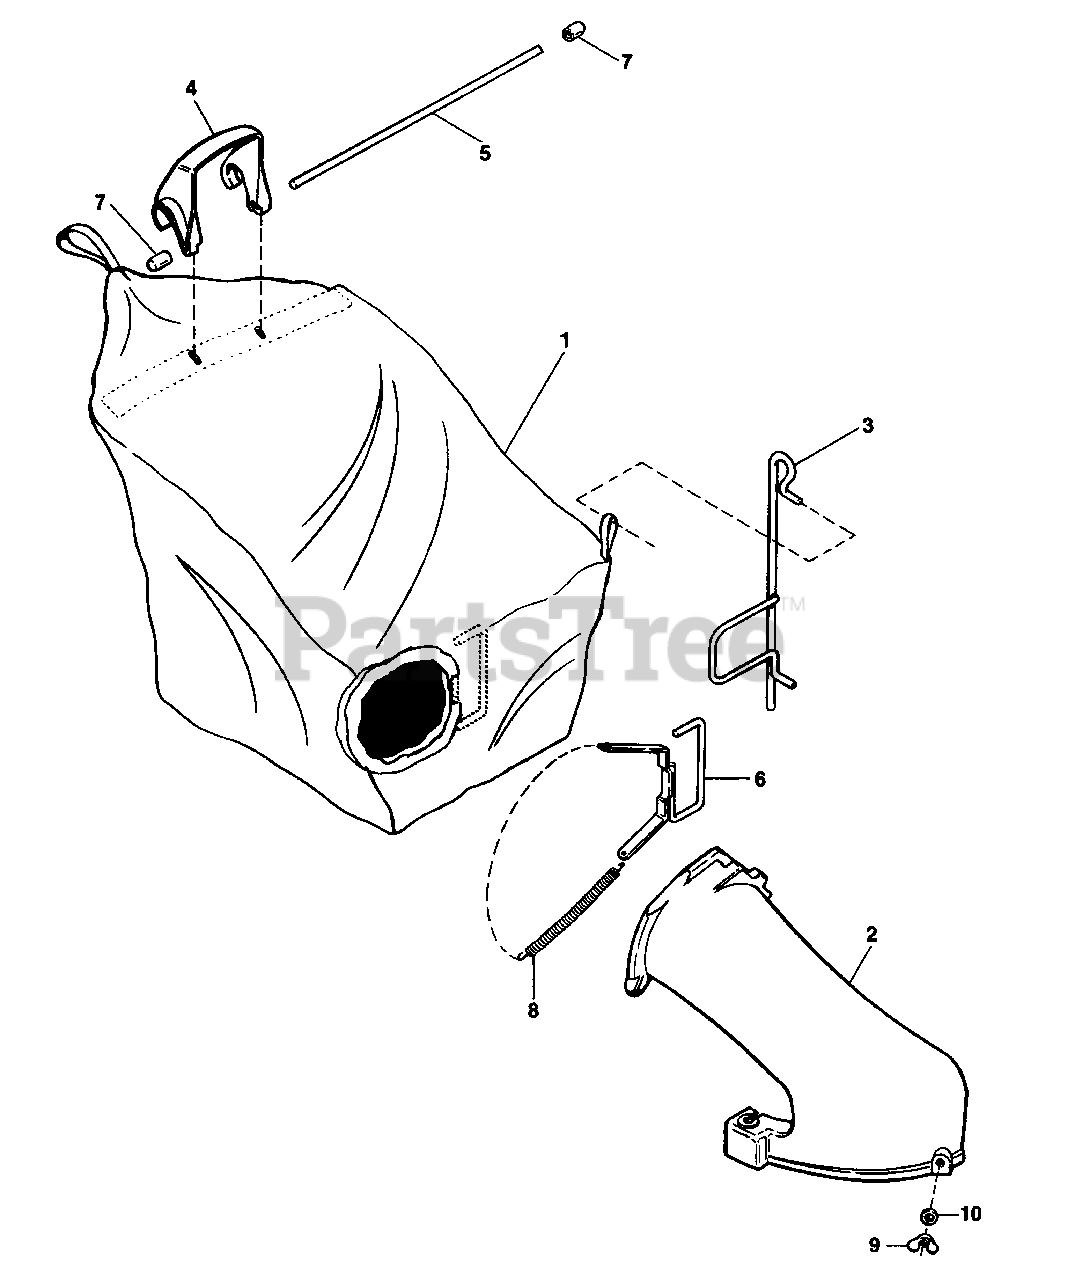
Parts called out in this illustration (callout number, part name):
1	GRASS BAG
2	CHUTE, Discharge
3	SUPPORT, Bag
4	HANDLE, Upper
5	ROD, Upper Handle
6	HANDLE & FRAME
7	RETAINER, Upper Handle
10	WASHER, Flat
